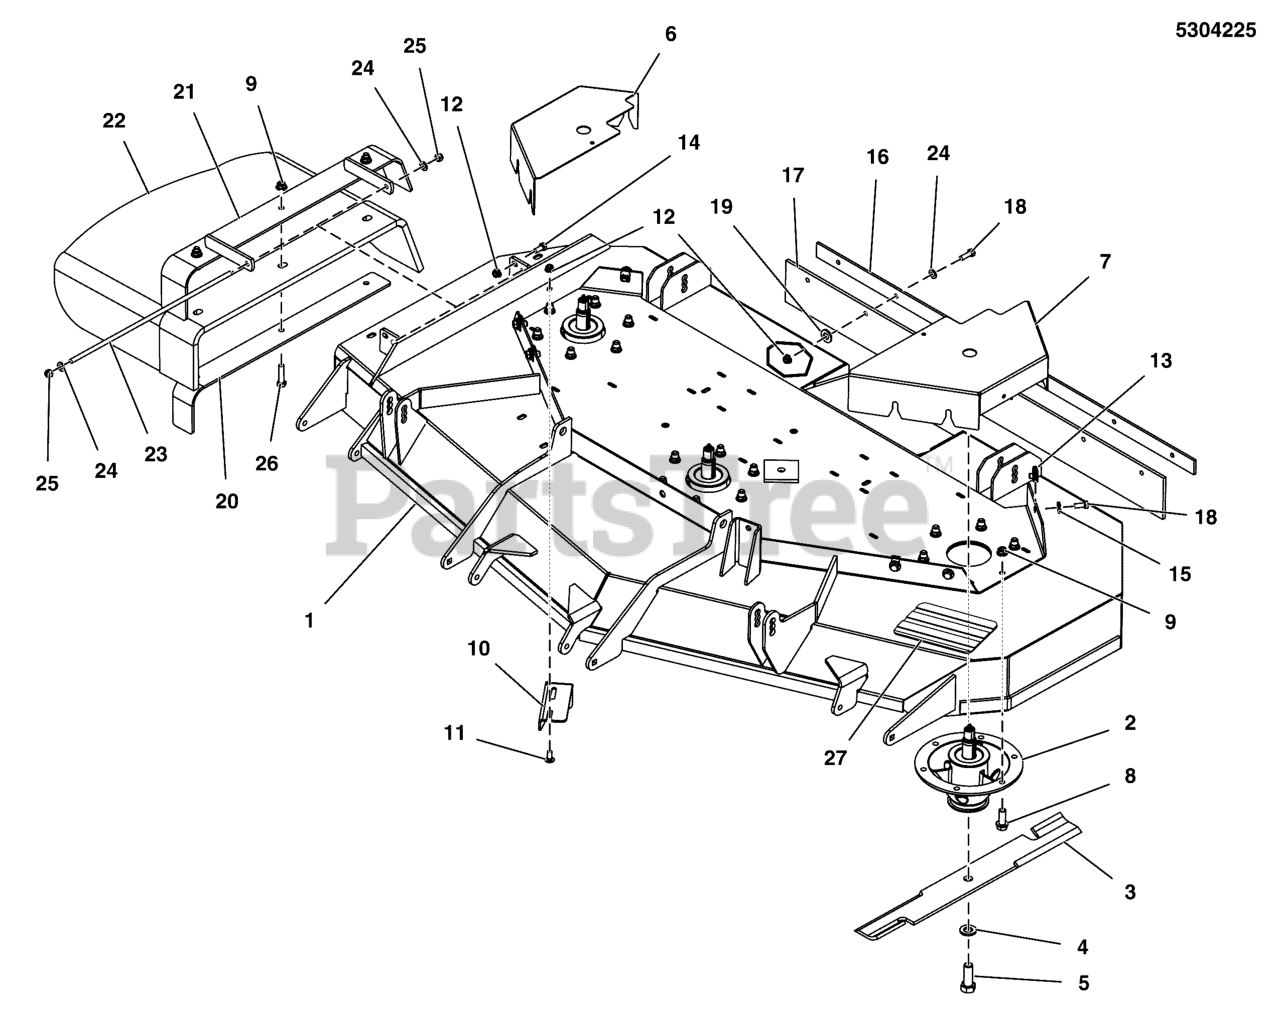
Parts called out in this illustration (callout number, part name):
1	DECK SHELL W/ DECALS, 61SD, IS2600Z-DOM (5413818B)
1	DECK SHELL W/DECALS, 2600Z-61 (5422059B)
2	SPINDLE ASSM, CAST IRON 8.0 - 6-BOLT
3	BLADE SET, 61 DECK (3)
4	WASHER, BLADE BOLT, 9/16" F436, CZ
5	BOLT, 5/8-11 X 1-3/4 GD8
6	GUARD, 61", RH - RED
7	GUARD, 61", LH - RED
8	BOLT, 3/8-16 X 1, FLANGE, GD 5, CZ
9	NUT, 3/8 - 16 HEX NYLOCK FLANGE
10	PLATE, DEFLECTOR - BLK
11	BOLT, 5/16-18 X 3/4, CARRIAGE, GD5, CZ
12	NUT, 5/16-18 HEX NYLOCK FLANGE NUT
13	BODY CLIP, 5/16-18-7GA MATERIAL
14	BOLT, 5/16-18 X 3/4 GD5
15	WASHER, 5/16 GRADE 9, FLAT
16	PLATE, SUPPORT - BLK
17	FLAP, STRIPER, 61 DECK
18	BOLT, 5/16-18 X 1" GRD5 YZ
19	5/16" PUSH-ON NUT RETAINER, STL, CZ
20	SUPPORT, DISCHARGE CHUTE - BLK
22	CHUTE, RUBBER DISCHARGE (5104442)
23	ROD, MOUNT, CHUTE, 61, CZ
24	WASHER, 5/16" SAE
25	NUT, 5/16-24 HEX NYLON LOCK
26	BOLT, 3/8-16 X 1-1/2, CARRIAGE, GD5, CZ
27	SAFETY WALK, 9.75 X 6.00
